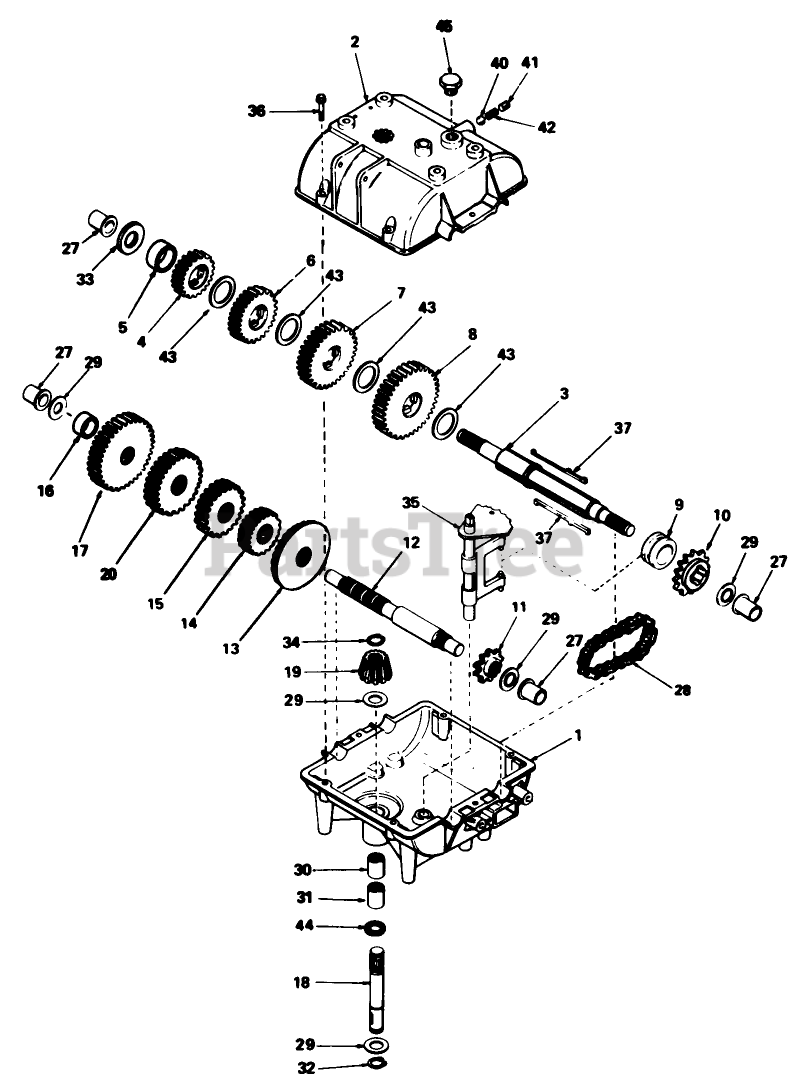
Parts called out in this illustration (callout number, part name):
1	Case-Transmission
2	Cover-Transmission
3	Shaft-Output
4	Gear-Spur, 25 Teeth
5	Spacer
6	Gear-Spur, 30 Teeth
7	Gear-Spur, 35 Teeth
8	Gear-Spur, 37 Teeth
9	Collar-Shift
10	Sprocket-18 Teeth
11	Sprocket-9 Teeth
12	Countershaft
13	Gear-Bevel, 42 teeth
14	Gear-Spur, 12 Teeth
15	Gear-Spur, 15 Teeth
16	Spacer
17	Gear-Spur, 25 Teeth
18	Shaft-Input
19	Bevel Pinion-Input
20	Gear-Spur, 20 Teeth
27	Bushing-Flange
28	Chain-Roller #41
29	Washer
30	Bearing-Needle
31	Bearing-Needle
32	Ring-Snap
33	Washer
34	Ring-Retainer
35	Rod and Fork ASM
36	Ring Set (.020 O S)
40	Ball-Steel
41	Screw-Set
42	Spring
43	Washer
44	O Ring
